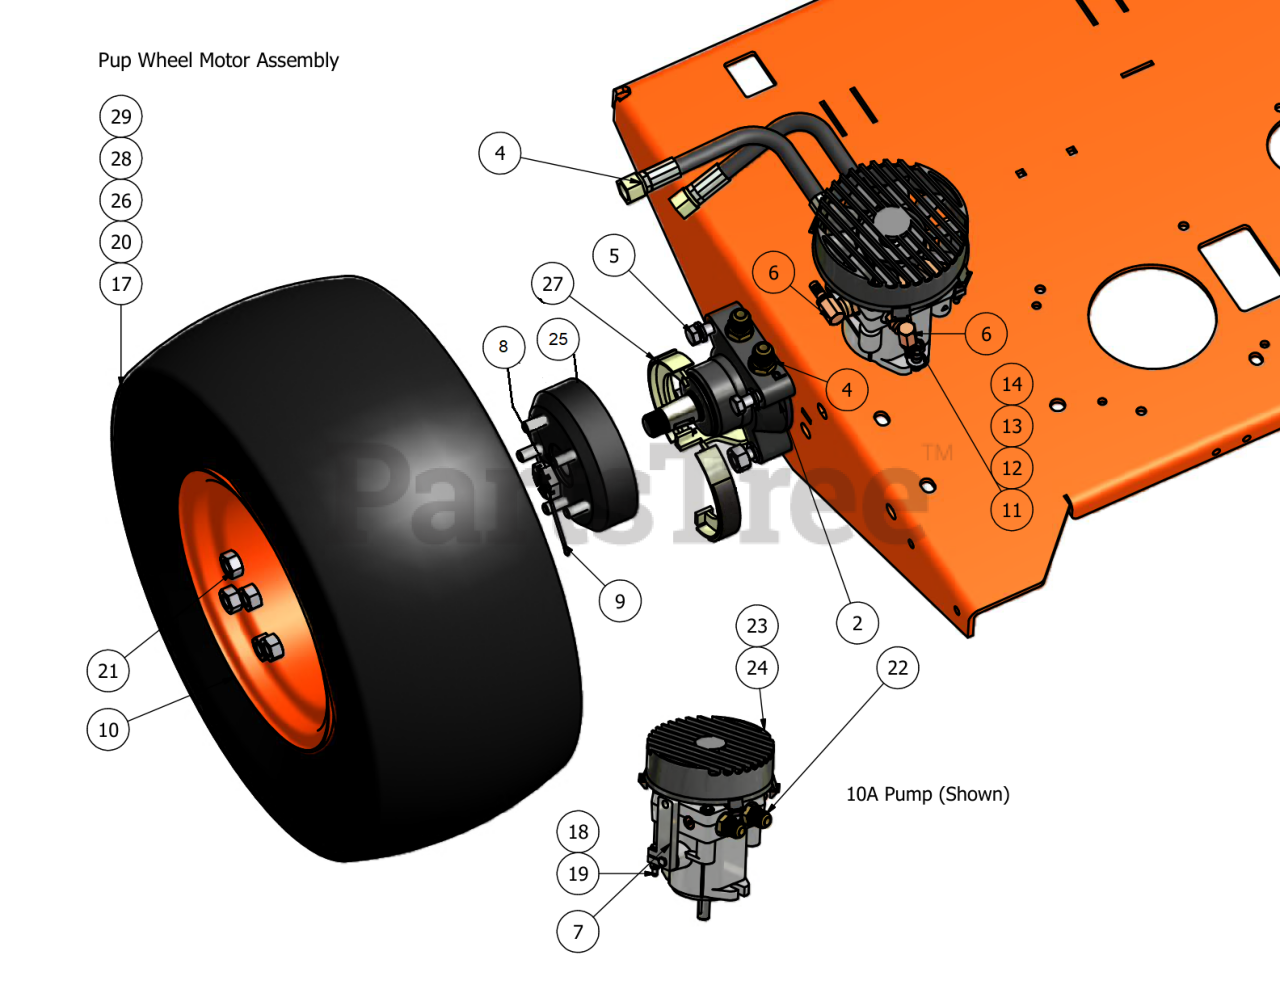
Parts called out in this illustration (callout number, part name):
2	Brake & Wheel Motor(
3	Hydraulic Fitting (Wheel Motor)
4	Hydralic Hoes
5	1/2" x 3" Hex Bolt
6	3/8"x9/16" Male Fitting
7	Pup Pump Arm
8	Castle Nut
9	1/8" x 2 1/4" Cotter Pin
10	12' Rim -60"&72" Cut
11	3/8" x 1 1/2" Hex Bolt
12	3/8" Hex Nut
13	3/8" Lock Washer
14	3/8" Flat Washer
15	Hydraulic Pump (10A) Left
16	Hydraulic Pump (10A) Right
17	24x12-12 Tire 60"&72" Cut
18	1/4" Nylock Nut
19	1/4"x 1 1/2" Bolt Straight Thread
20	24" Tire and Wheel Assembly
22	Hydraulic Fitting
23	Hydraulic Fan
25	Brake Drum
26	23x10.50-12 Tire & Wheel
27	Brake Pads
28	12" Rim 48"&52" Cut
29	23x10.50-12 Tire
